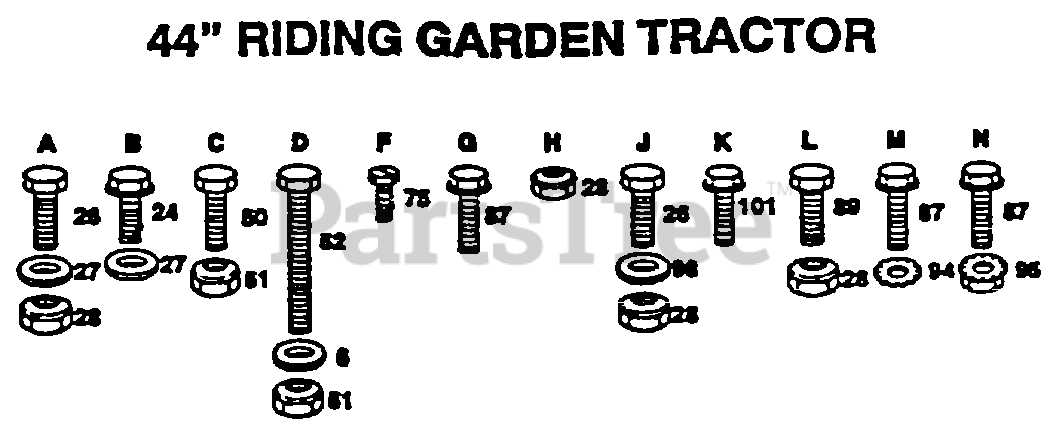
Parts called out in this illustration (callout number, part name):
6	WASHER
24	SCREW
26	BOLT
27	WASHER
50	BOLT
52	BOLT HEX
61	WASHER
75	SCREW LT
87	SCREW LT
94	LOCKWASHER
96	NUT
